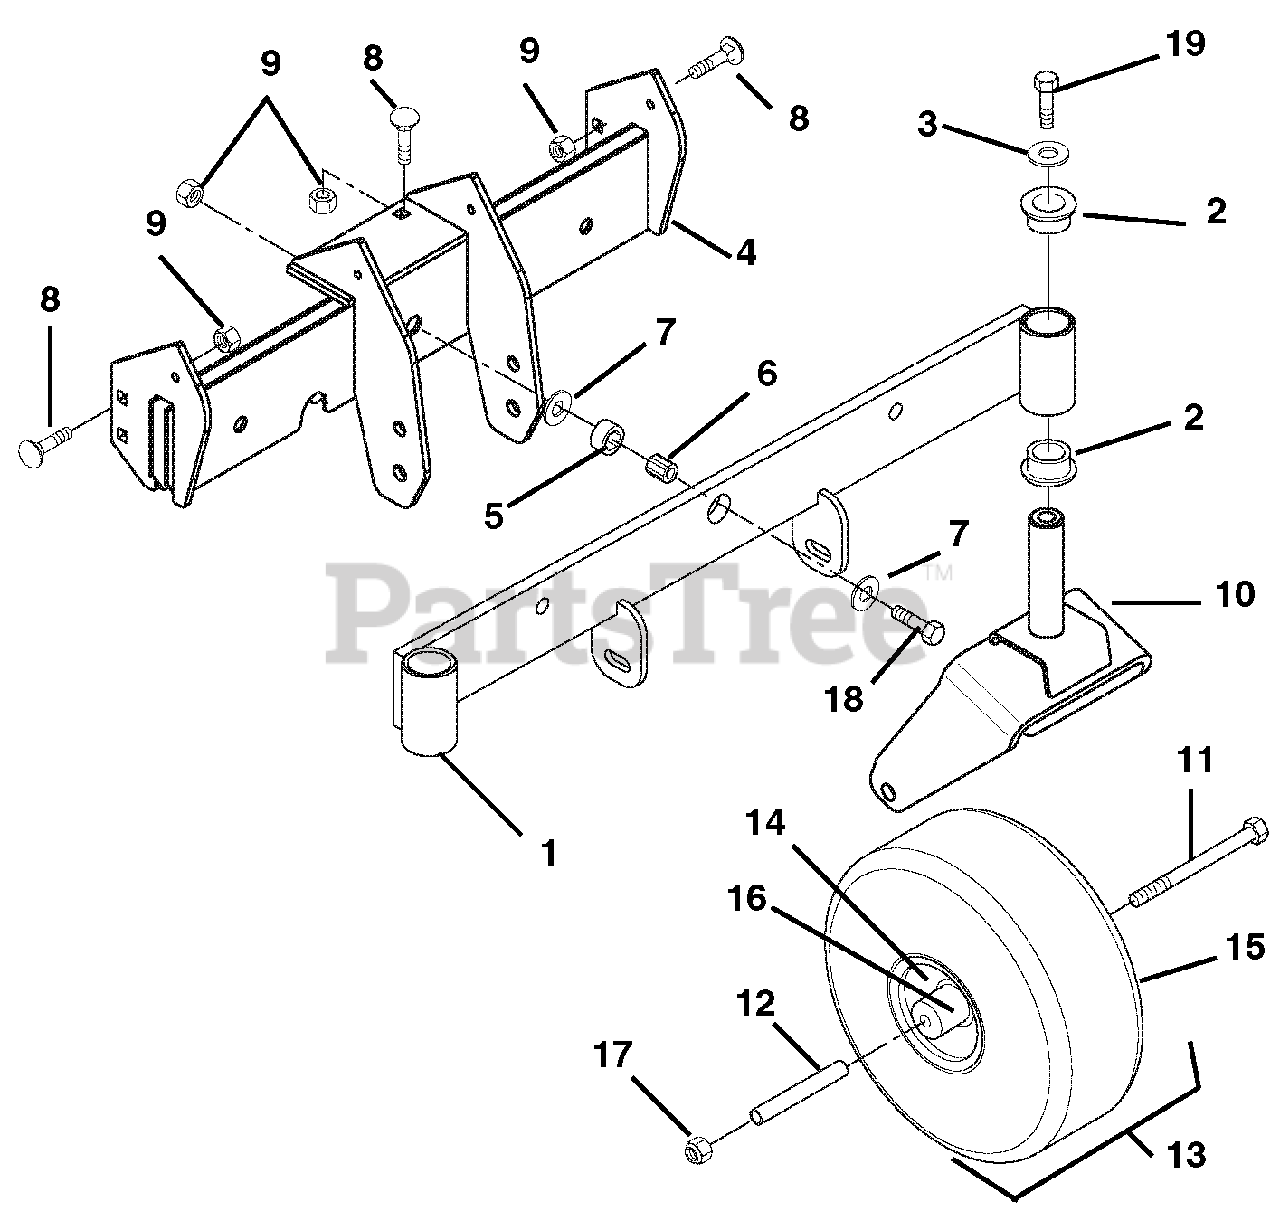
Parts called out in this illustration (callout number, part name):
1	Axle Weldment
2	Bushing-Flange 1.020 x 1.385 x .75 x 1.75
3	Washer-Flat-Steel .38 x 1.50 x .125
4	Axle Frame Weldment
5	Bushing-Sleeve .626 x 1.000 x .524
6	Bushing-Sleeve .377 x .623 x .775
7	Washer-Flat-Steel .375 x 1.125 x .065
8	Bolt-Round Head Square Neck .38-16 x .75 Grade 5
9	Nut-Locking-Center .375-16
10	Fork-Caster
11	Bolt-Hex .50-13 x 6.50
12	Bushing-Caster Fork
13	Wheel & Tire 11 x 4.00-5
14	Rim Assembly
15	Tire
16	Bearing
17	Nut-Locking-Center .50-13 Grade 5
18	Bolt-Hex .38-16 x 1.75 Grade 5
19	Screw-Tapping .38-16 x 1.25 Hex Washer Head
